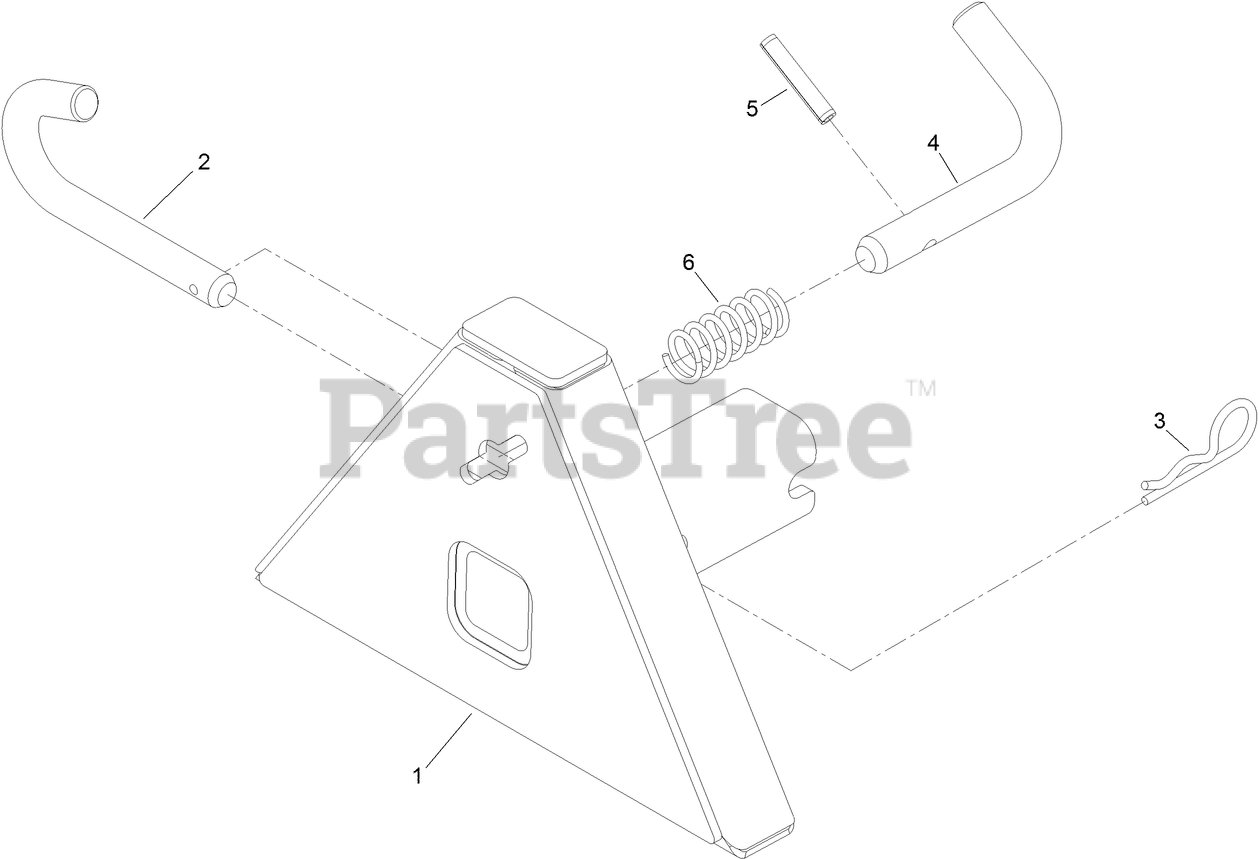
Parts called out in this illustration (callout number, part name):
1	ATTACHMENT ASM
2	PIN-ATTACH
3	PIN-HAIR
4	PIN-LYNCH
5	PIN-SPRING, SLOTTED
6	SPRING-COMPRESSION
